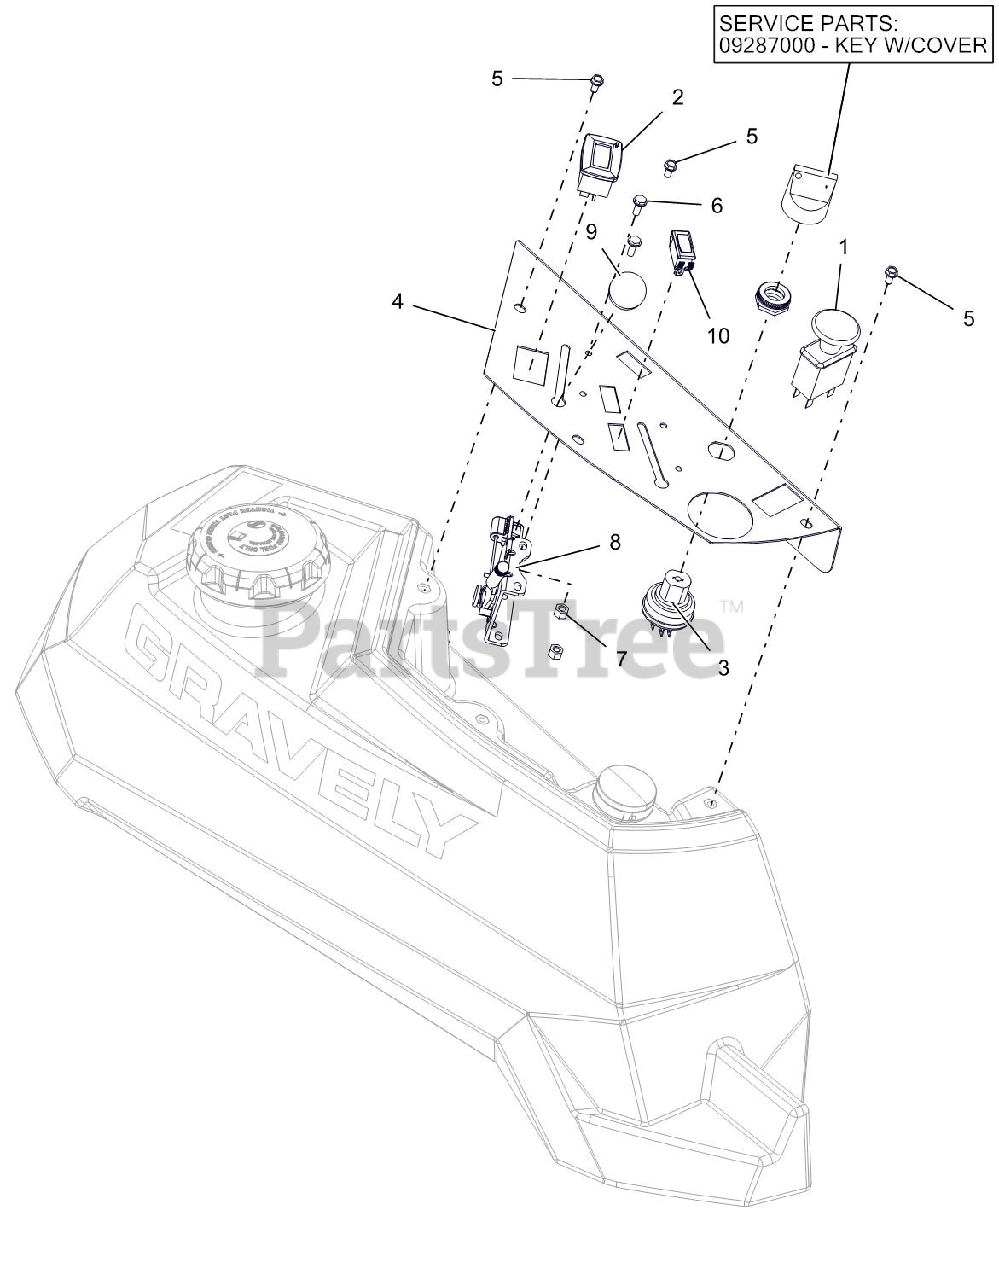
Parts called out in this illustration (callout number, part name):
1	SWITCH, CLUTCH
2	METER, HOUR W/MAINTENANCE
3	SWITCH, IGNITION
4	PANEL, PT100 CONTROL (RED)
5	SCR-MCH 10-24X.38 HWHSTAINLESS
6	SCR-MCH 10-24X.5 HWH YWZC
7	NUT-LK-NYL #10-24 YWZC
8	CABLE, PRO - CONTROL 31.50"
9	KNOB, CONTROL
10	LIGHT, INDICATOR
11	KEY W/COVER
